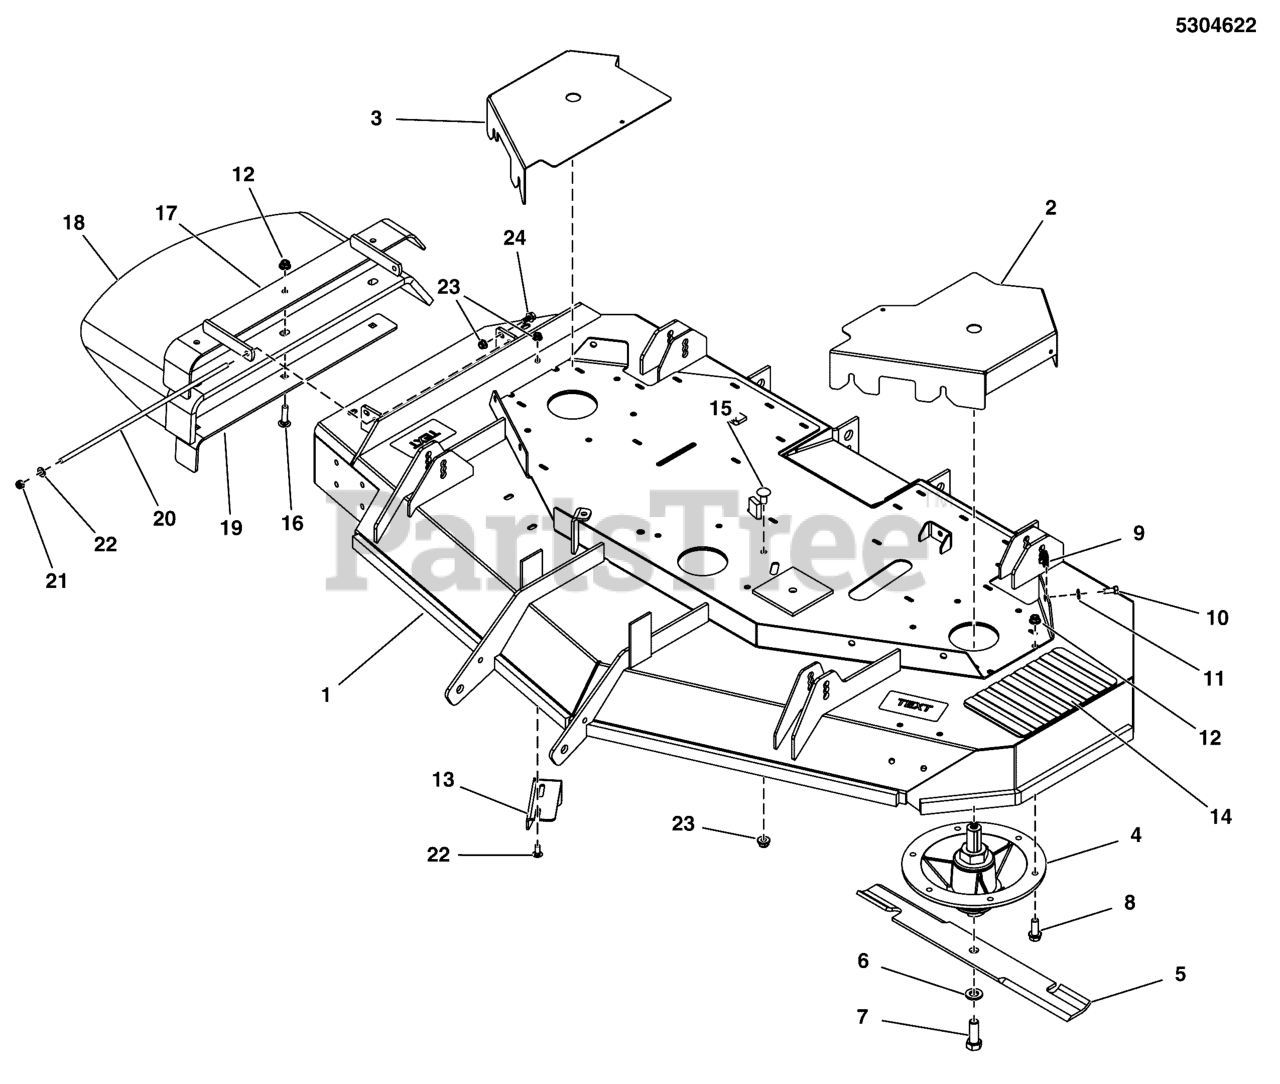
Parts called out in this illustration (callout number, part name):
1	DECK SHELL W/DECALS, 61, F320Z (5415350B)
1	DECK SHELL W/DECALS, F320Z-61 (5417033B)
2	GUARD, IS3200Z, LH 61" - RED
3	GUARD, MOWER DECK, IS3200-61, RH - RED
4	SPINDLE ASSEMBLY
5	BLADE SET, 61 DECK (3)
6	WASHER, BLADE BOLT, 9/16" F436, CZ
7	BOLT, 5/8-11 X 1-3/4 GD8
8	BOLT, 3/8-16 X 1-1/4, FLANGE, GD 5, CZ
9	BODY CLIP, 5/16-18-7GA MATERIAL
10	BOLT, 5/16-18 X 1" GRD5 YZ
11	WASHER, 5/16 GRADE 9, FLAT
12	NUT, 3/8 - 16 HEX NYLOCK FLANGE
13	PLATE, DEFLECTOR - BLK
14	SAFETY WALK, 9.75 X 6.00
15	BOLT,3/8-16X1-1/4,GR5,CARRIAGE,ZC/CL
16	BOLT, 3/8-16 X 1-1/2, CARRIAGE, GD5, CZ
18	CHUTE, RUBBER DISCHARGE (5104442)
19	SUPPORT, DISCHARGE CHUTE - BLK
20	ROD, MOUNT, CHUTE, 61, CZ
21	NUT, 5/16-24 HEX NYLON LOCK
22	BOLT, 5/16-18 X 3/4, CARRIAGE, GD5, CZ
23	NUT, 5/16-18 HEX NYLOCK FLANGE NUT
24	BOLT, 5/16-18 X 3/4 GD5
